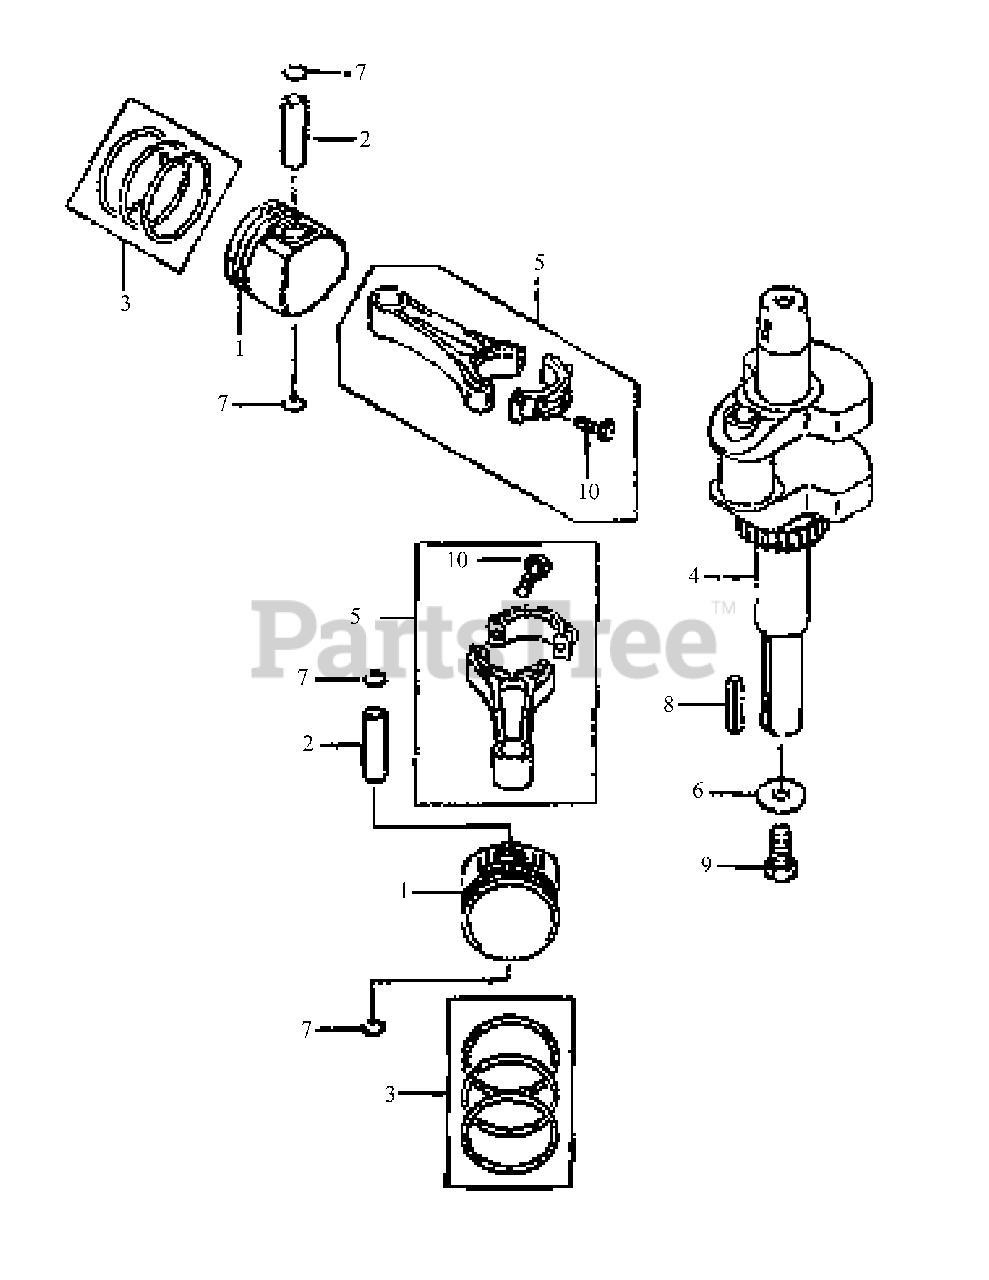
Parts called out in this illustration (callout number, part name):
1	Piston, Engine
3	Ring, Set Piston
5	Rod, Connecting
6	Washer 12.5x32x3.2
7	Ring, Snap
9	Bolt 7/16-20 unf
10	Bolt, Flange
